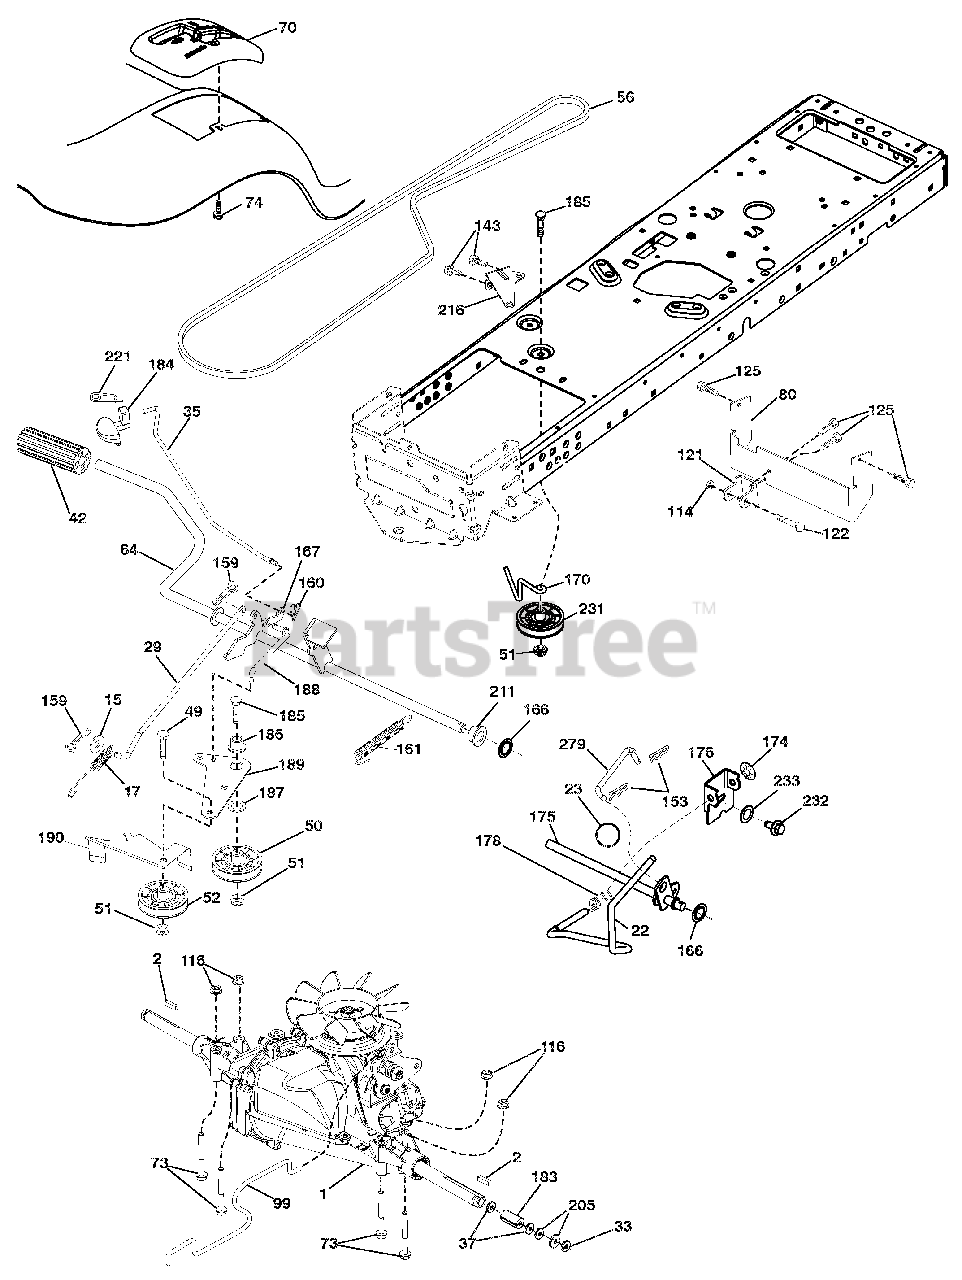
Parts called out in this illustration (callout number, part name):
1	TRANSAXLE, T2-CDBE-5X1A-18C1(581115601)(ORDER PARTS FROM TRANSAXLE MANUFACTURER.)
2	KEY.SQUARE.2.0 X .1845/.1865
15	WASHER.13/32 X 13/16 X 16 GA.
17	SPRING.BRAKE.GT.TEX
22	ROD.SHIFT.FENDER.TLT.2006
29	BRAKE ROD
33	E-RING.#5133-75
35	ROD, BRAKE, PARK
37	WASHER.25/32 X 1 1/4 X 16 GA.
42	COVER PEDAL BLK ROUND
49	BOLT.RDHD.3/8-16UNCX1-3/4.GR5
50	IDLER.FLAT.910"OFFSET
51	Nut, Hex, Flangelock 3/8-16
52	IDLER.V-GROOVE.910"OFFSET
56	V-BELT.DRIVE
64	SHAFT ASM.PEDAL.BRAKE CONTROL
70	CONSOLE SHIFT STL HYD BLACK TX
73	BOLT.HEX.FLGHD.5/16-18.GR.5
74	SCREW.HEX.WSH.HI-LO.1/4X1/2UNC
80	STRAP TORQUE
99	ROD.ASM.BYPASS.SPRING.T2.FS
114	Locknut, Washer Insert 5/16-18
116	Nut, Lock Hex Flange 5/16-18 u
121	BRACKET.STRAP.TORQUE.T/A.3500
122	BOLT.5/16-18 x 2.50
125	SCREW.5/16-18X3/4.SMGML.TAP/BL
143	SCREW.THDROL.5/16-18 X 1/2TYTT
153	RETAINER SPRING
159	PIN.COTTER.1/8 X 3/4.CAD.
160	RETAINER.CLIP(M).DIA.290
161	SPRING.RETURN.CLUTCH.6.75
166	NUT PUSH .625
167	LATCH.BRAKE.PARKING
170	KEEPER.CENTER SPAN.1.688
174	NUT.PUSH..500
175	SHAFT ASM.SHIFT.T2/K66.FS.TX
176	ARM.CLEVIS.ROD.SHIFT
178	SPRING.SHIFT.GT.2006
183	SPACER.AXLE.PVST
184	HANDLE PARKING BRAKE
185	BOLT.RDHD.3/8-16UNC X2-3/4 GR5
186	SPACER.RETAINER
187	WASHER.13/32 X 2 X 10 GA.
188	LINK.CLUTCH.GROUND DRIVE
189	BELLCRANK.GROUNDRIVE.NSTG/NSTL
190	KEEPER.BELLCRANK.DRIVE.GROUND
205	WASHER.25/32 X 1-5/8 X 16GA.
211	BUSHING.SHAFT.BRAKE.HAND CONTR
216	BRACKET.PULLEY.IDLER.WTEX
221	RETAINER.SPRING.CLIP.HANDLE
231	IDLER.V-GROOVE.1.688"OFFSET
232	BOLT.FIN HEX.7/16-14X1 GR5
233	WASHER.SERRATED
279	LINK SHAFT
